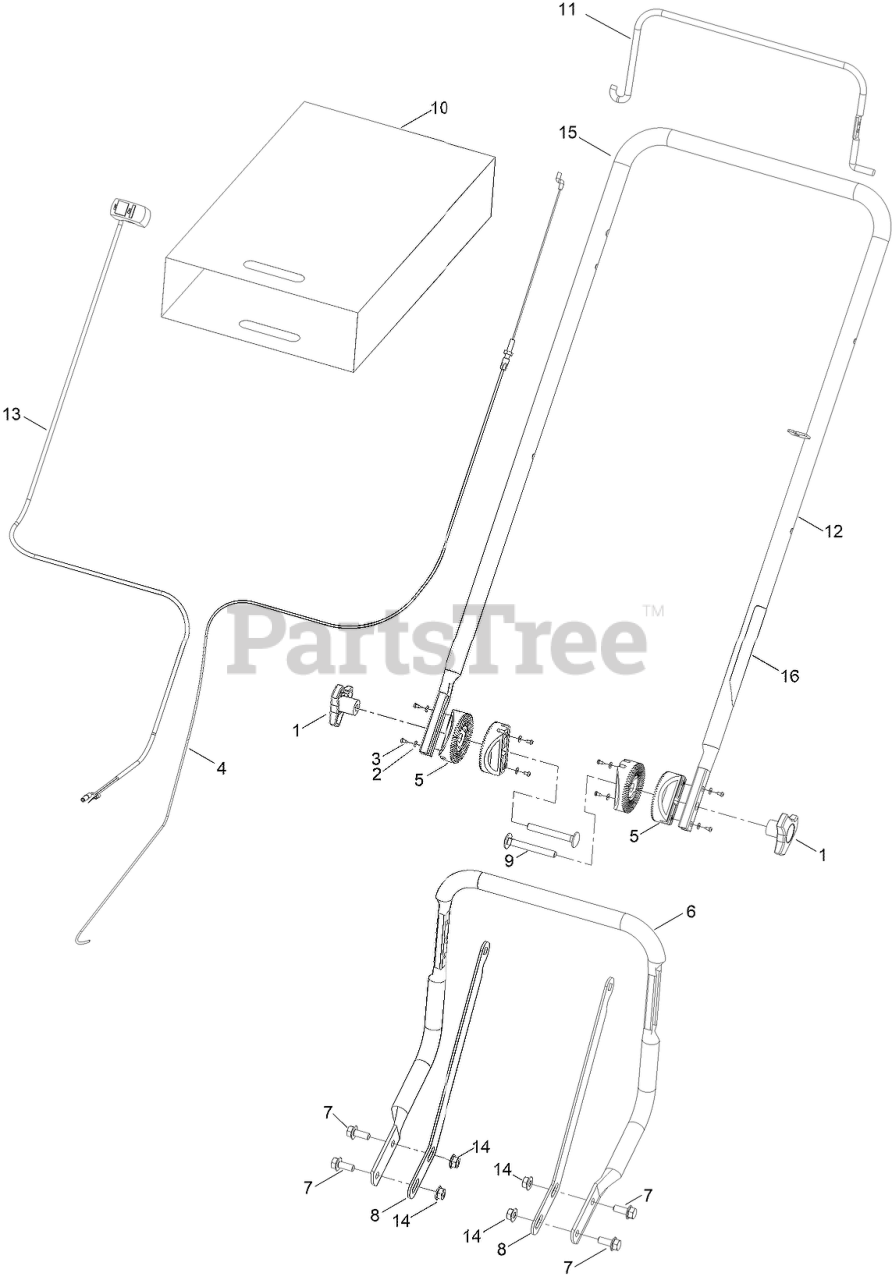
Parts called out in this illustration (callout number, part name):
1	KNOB-HANDLE
2	WASHER-PLAIN
3	SCREW-PPH
4	CABLE-CLUTCH
5	PIVOT-HANDLE
6	HANDLE-LOWER
7	SCREW-HHF
8	BRACKET-SUPPORT, HANDLE
9	BOLT-CARRIAGE
10	MANUAL ASM
11	BAIL-CLUTCH
12	HANDLE-UPPER
13	SWITCH-STOP
14	NUT-HEX
15	DECAL-ARRESTOR, SPARK
16	DECAL-HANDLE
